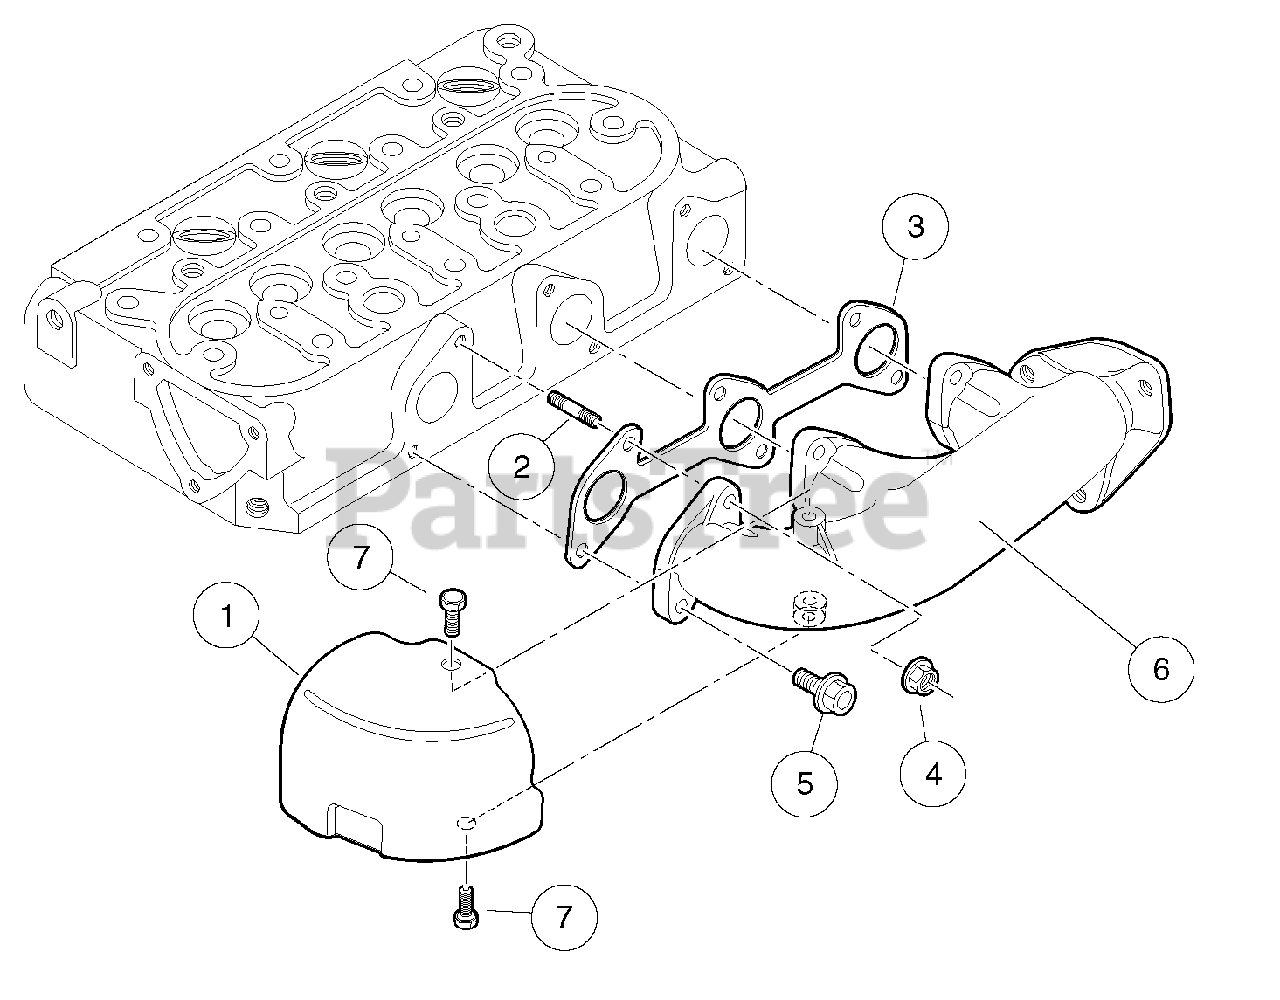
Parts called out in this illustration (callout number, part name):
1	Cover, Heat Proof
2	Stud, M6 X 26
3	Gasket, Ex-manifold
4	Nut, Flange, M6, Ubs
5	Bolt, Flange Head, M6 X 1 X 16
6	Manifold, Exhaust, D722
7	Bolt, D722, Exhst Manfld Cover
